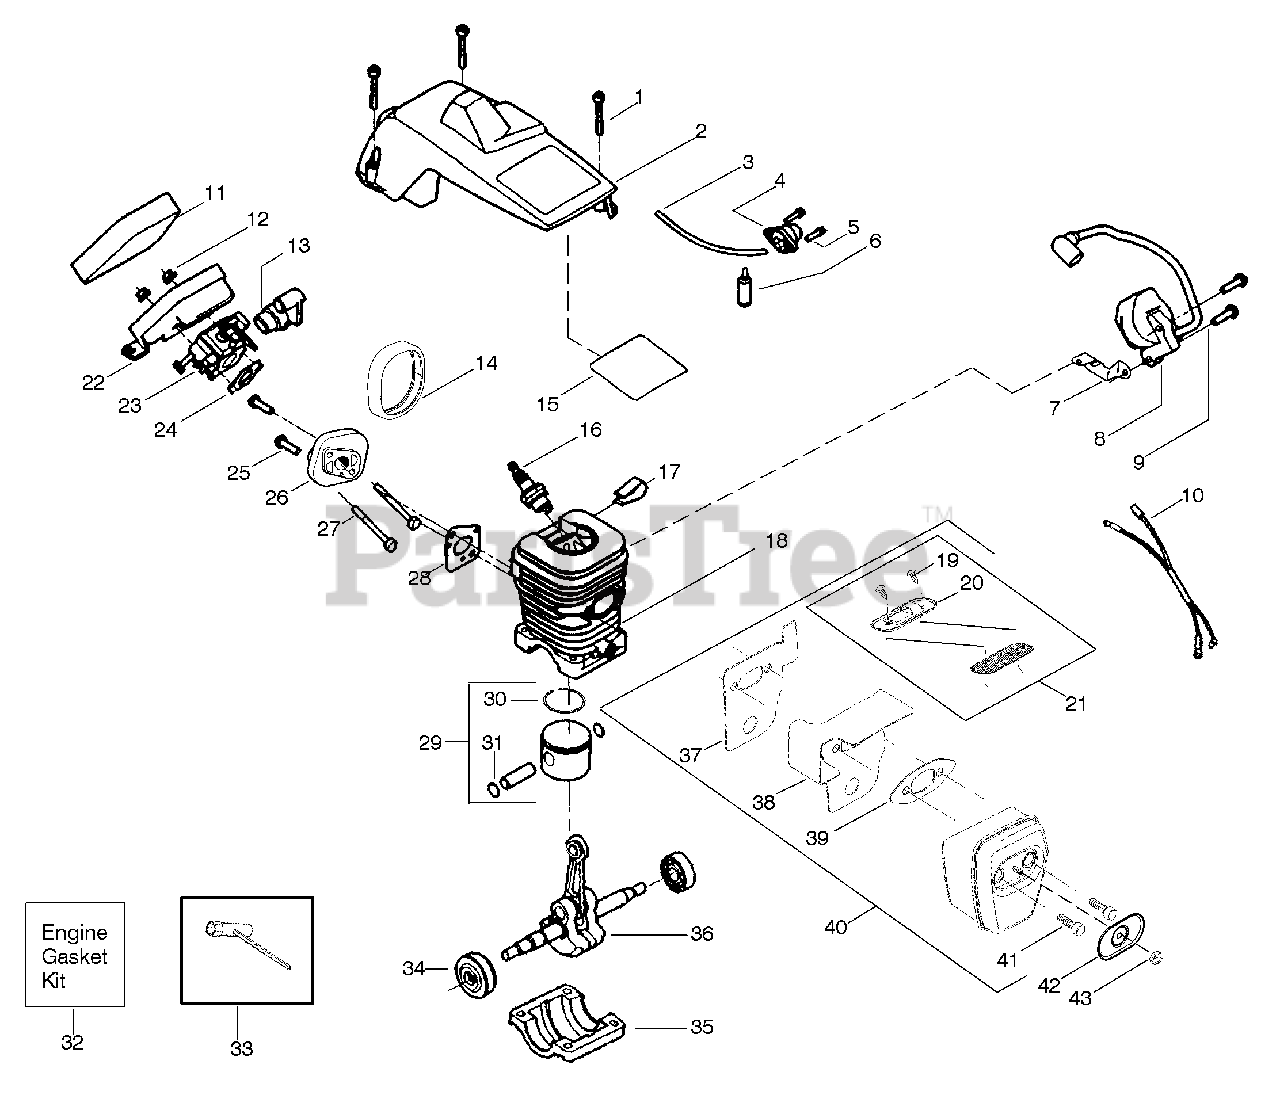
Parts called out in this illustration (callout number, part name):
2	Assy-Cylinder Shield
3	Kit-Fuel Line (Small)
4	Assy-Air Purge
6	Assy-Fuel Pick-up
7	Strap-Ground
8	Ignition Module
10	Assy-Wire Harness
11	Foam-Air Filter
13	Grommet-Carb Adjust
14	Seal-Carb Adapter
15	Reflector-Heat
16	Spark Plug (RCJ-7Y)
17	Clip-High Tension Lead
18	Cylinder
19	Screw-Outlet cover
20	Cover- Outlet
21	Kit-Spark Arrestor
22	Air Filter Housing
23	Kit-Carburetor Zama (W-20)
23	Kit-Carburetor Walbro
24	Gasket-Carb. (kit)
26	Carb. Adapter
28	Gasket- Adaptor(kit)
29	Kit-Piston
30	Ring-Piston
31	Retainer-Piston Pin
32	Kit-Engine Gasket
33	Bar Wrench
34	Assy-Seal & Bearing
35	Cap-Crankcase
36	Assy-Crankshaft
37	Backplate
38	Guide-Outlet
39	Gasket-Muffler(kit)
40	Assy-Muffler
41	Bolt-Muffler
42	Cover-Bolt
43	Nut-Brass
